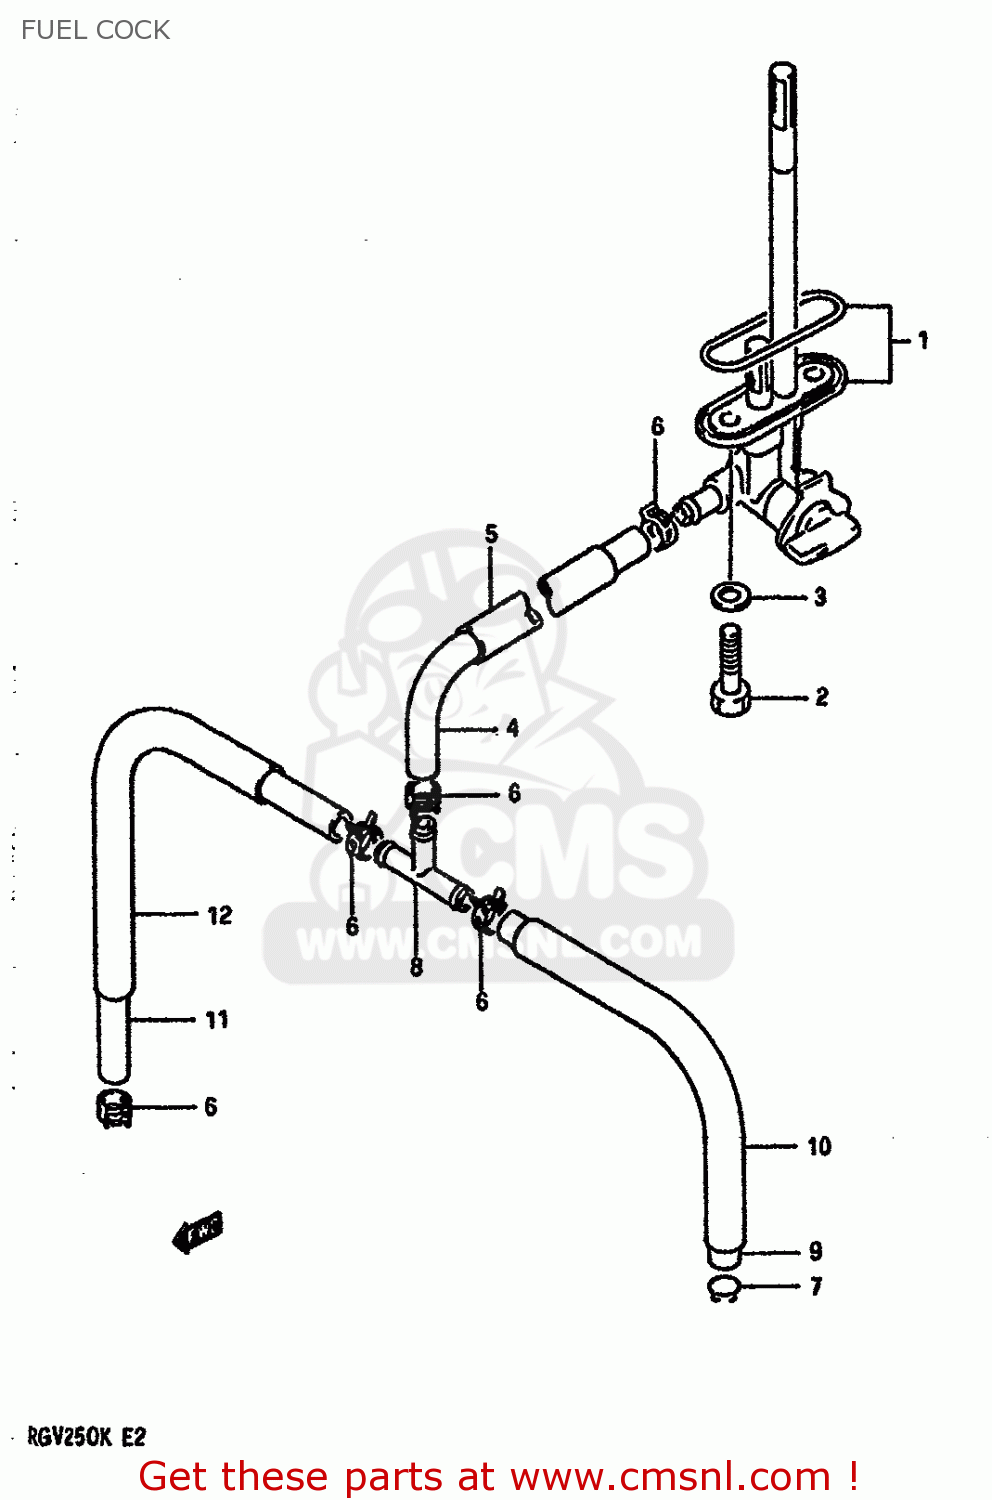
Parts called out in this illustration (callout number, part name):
1	COCK ASSY,FUEL
2	BOLT(6X20)
3	GASKET
4	HOSE
5	PROTECTOR
6	CLIP
7	CLIP
8	3-WAY [FILTER TO PUMP)
9	HOSE,LH
10	PROTECTOR
11	HOSE,LH
12	PROTECTOR
